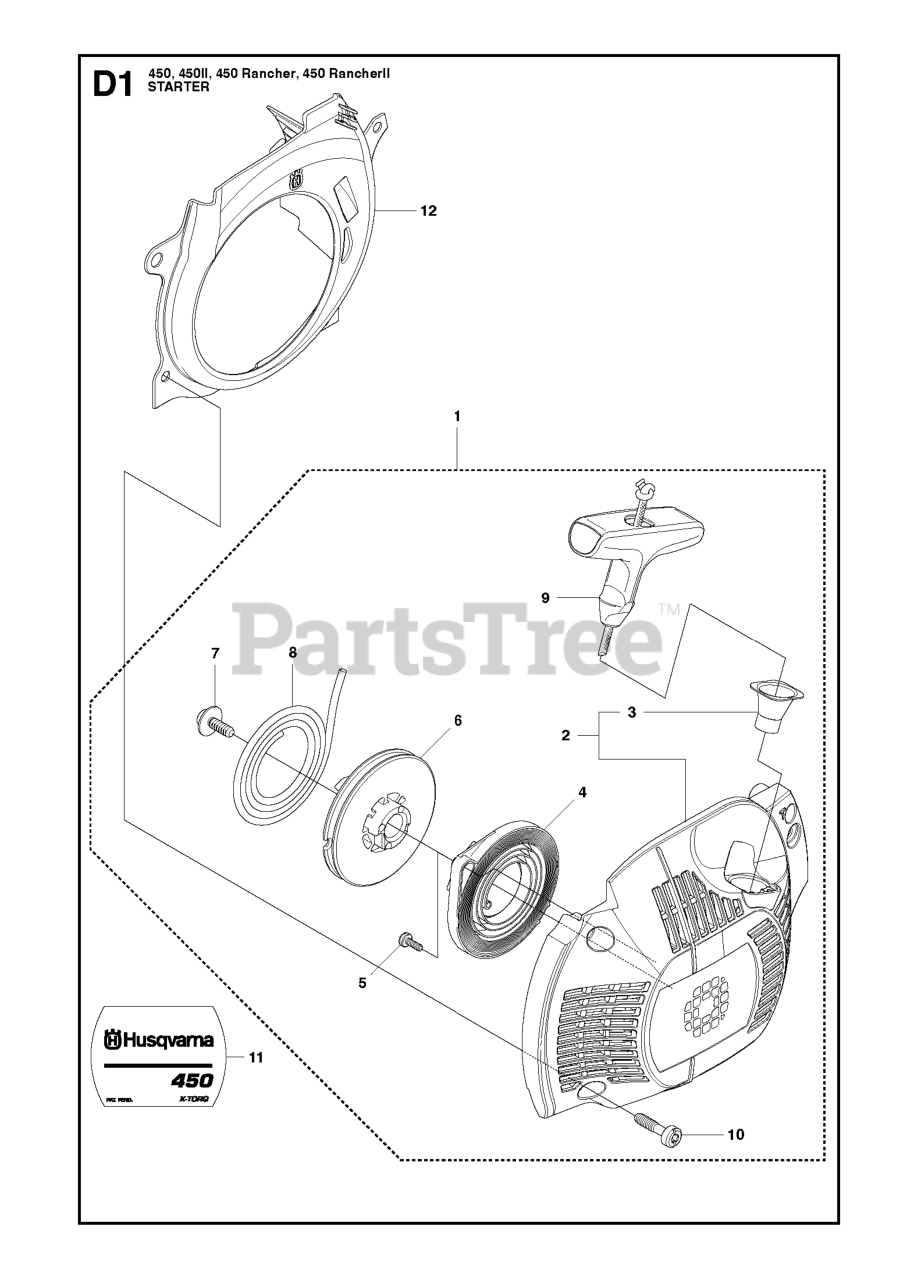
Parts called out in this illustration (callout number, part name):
1	STARTER ASSY
2	STARTER HOUSING
4	SPRING CASSETTE ASSY
6	STARTER PULLEY
8	STARTER ROPE
11	LABEL STARTER 450 RANCHER
11	LABEL
12	COOLING AIR CONDUCTOR
